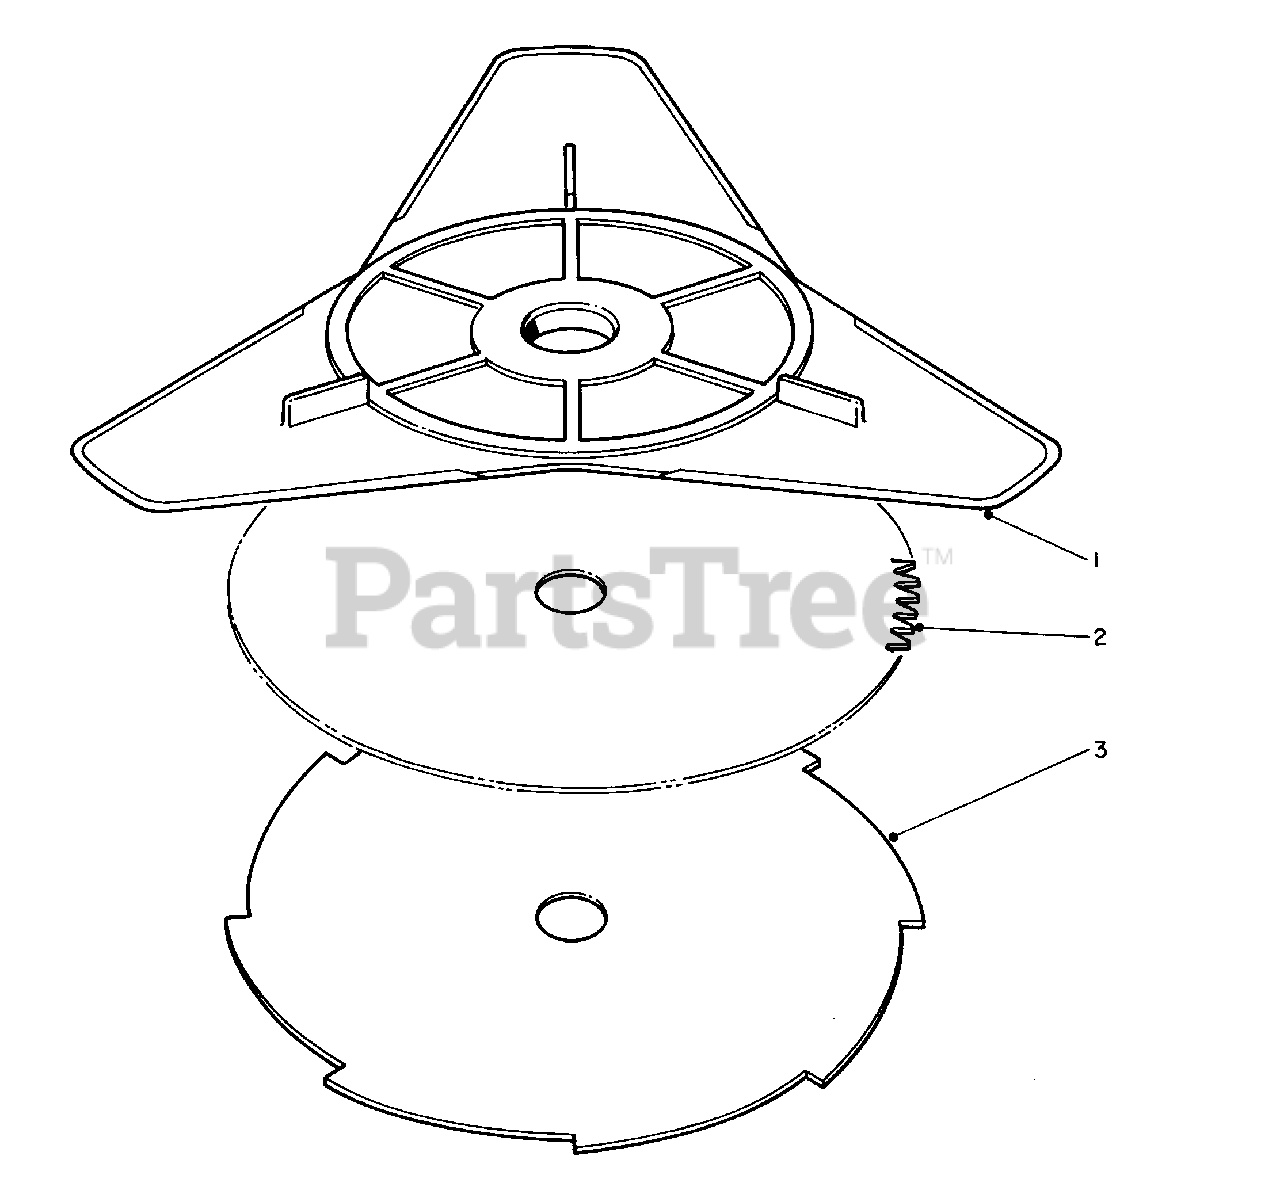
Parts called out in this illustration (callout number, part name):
1	Flex Blade
2	8" Blade (80)
3	8" Blade (8T)
